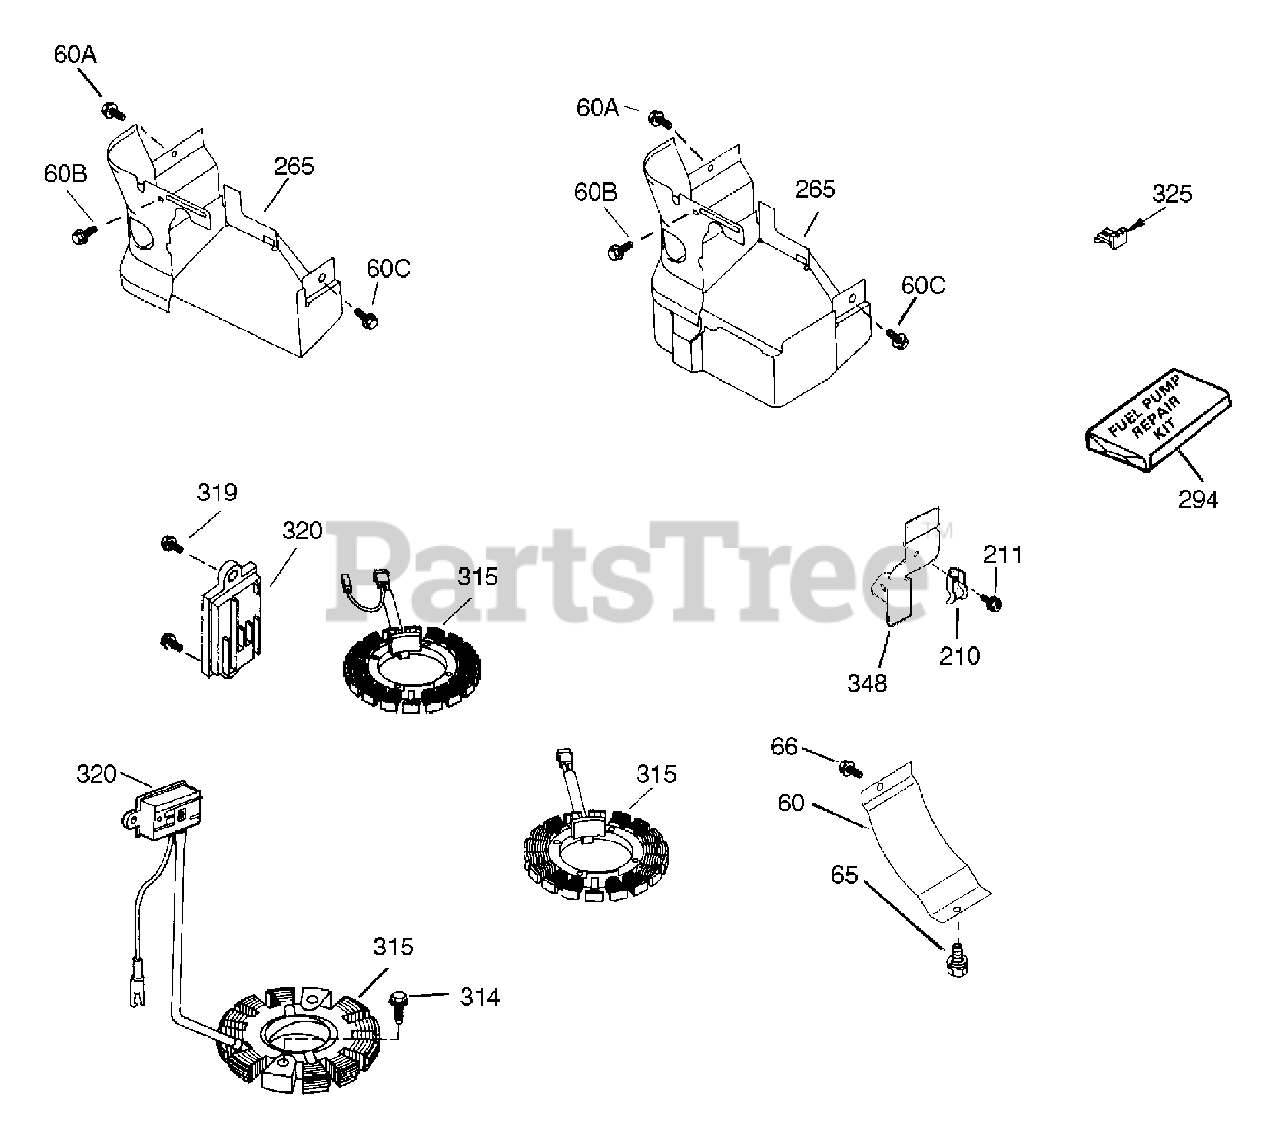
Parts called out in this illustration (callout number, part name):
60A	Screw, 5-16/18 x 17/32"
60B	Screw, 10-24 x 1/2"
60C	Screw, 1/4-20 x 1/2"
65	Screw, T-30, 1/4-20 x 1/2"
66	Screw, 1/4-20 x 1/2"
210	Conduit Clip
211	Screw, 10-32 x 3/8"
265	Cylinder Head Cover
294	Pulse Pump Repair Kit
314	Screw, T-15, 10-24 x 15/16"
315	Alternator Coil (3/5 Split)
